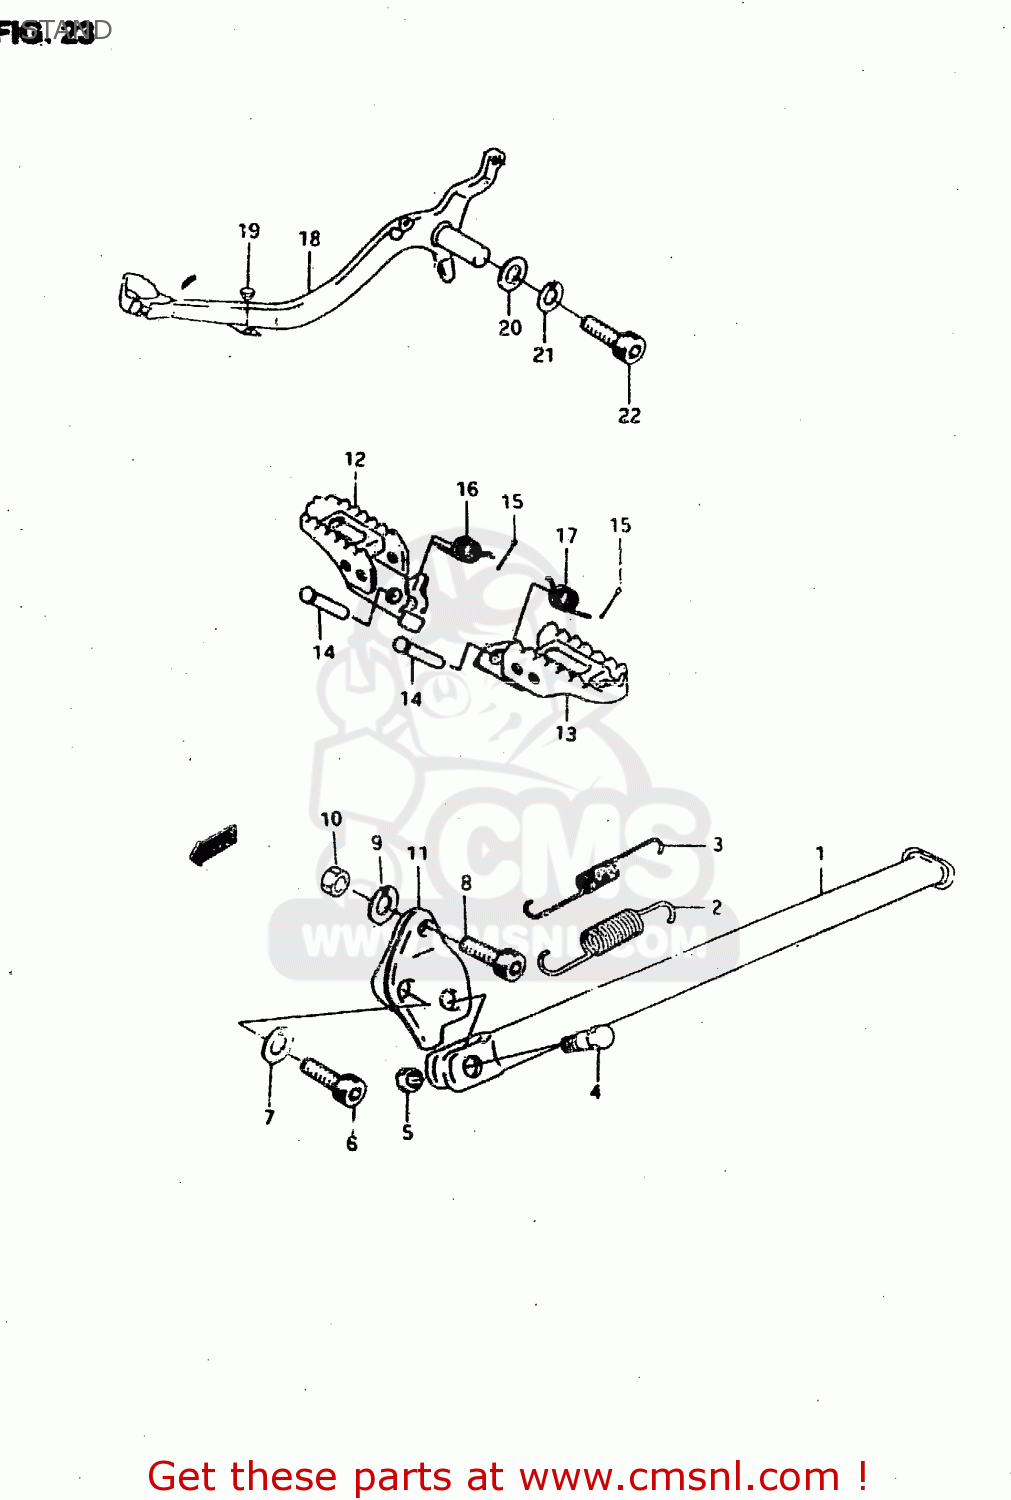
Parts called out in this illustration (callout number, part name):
1	STAND, PROP
2	SPRING
3	SPRING
4	BOLT L:30
5	NUT
6	BOLT
7	LOCK WASHER
8	BOLT
9	LOCK WASHER
10	NUT
11	BRACKET,PROP STAND
12	FOOTREST, FRONT RH
13	FOOTREST,FR,L
14	PIN
15	PIN 25X20
16	SPRING
17	SPRING LH
18	PEDAL BRAKE
19	CUSHION
20	WASHER
21	LOCK WASHER
22	BOLT,OIL FILLE
